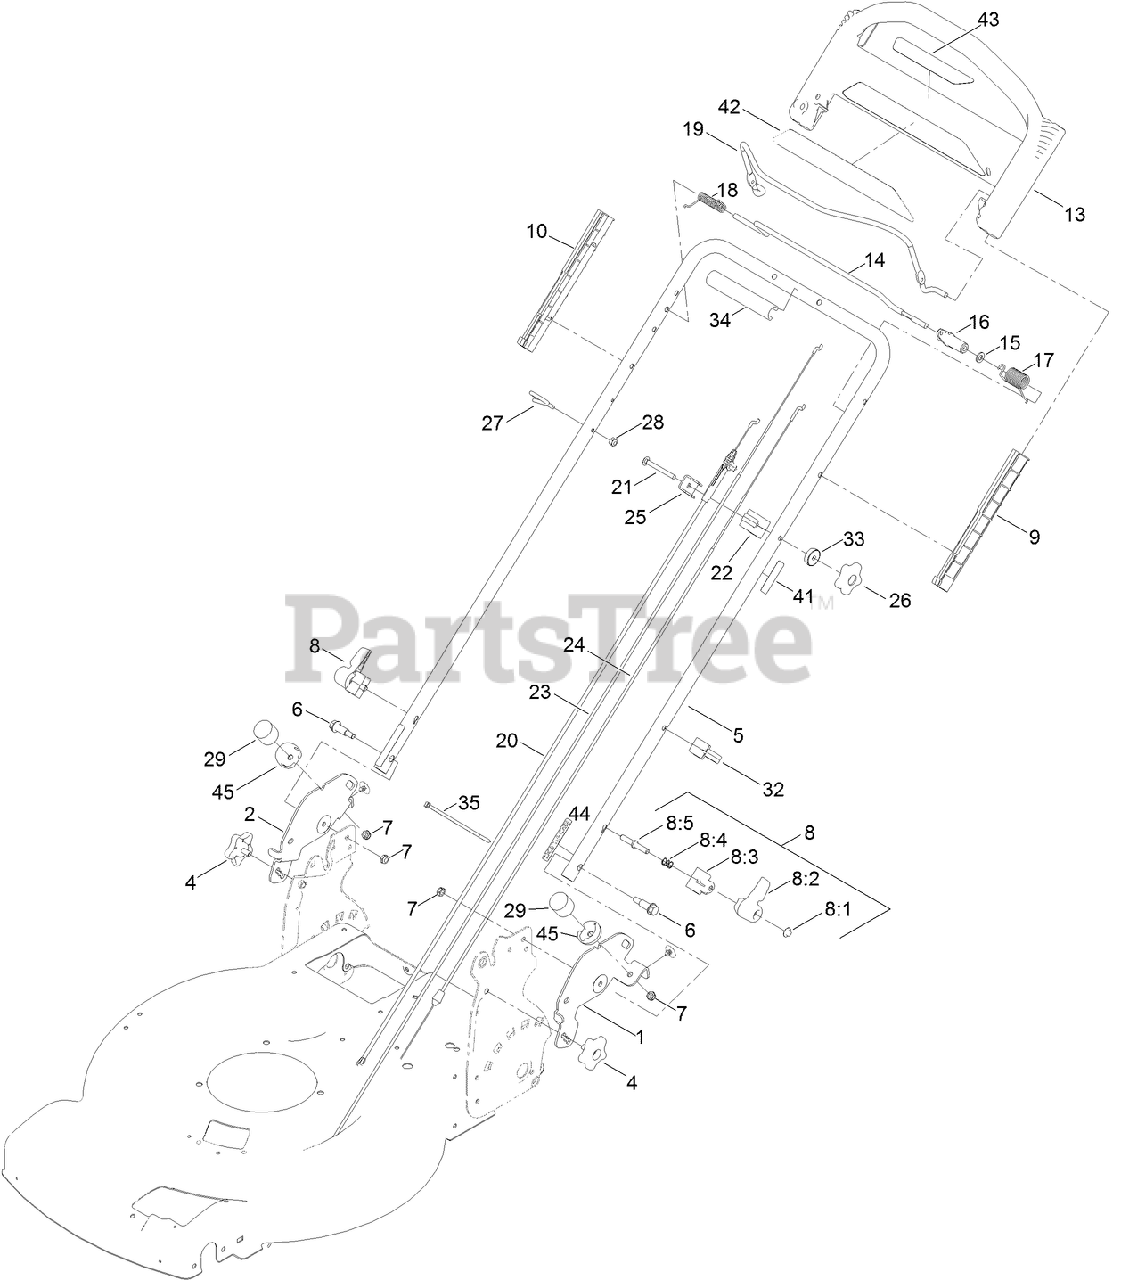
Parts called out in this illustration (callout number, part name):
1	BRACKET-FLOAT, LH
2	BRACKET-FLOAT, RH
4	KNOB-HANDLE
5	HANDLE-UPPER
6	BOLT-SHOULDER
7	NUT-LOCK, NI
8	QUICK RELEASE ASM
8:2	LEVER
8:3	ANCHOR-SPRING
8:4	SPRING-COMPRESSION
8:5	ROD-RELEASE
9	GUIDE-LH
10	GUIDE-RH
13	HANDLE-PACE, PERSONAL
14	BAR-CONTROL, TRACTION
15	WASHER-PLAIN
16	LEVER-TRACTION
17	SPRING-TORSION
19	BAIL-BRAKE
20	CABLE-BRAKE
21	SCREW-CARR
22	MOUNT-CABLE, TRACTION
23	CABLE-TRACTION, FRONT
24	CABLE-TRACTION, REAR
25	CLAMP-CABLE
26	KNOB-HANDLE, LOCKING
27	GUIDE-ROPE
28	NUT-LOCK, NI
29	BUMPER-RUBBER
32	GUIDE-CABLE
33	WASHER-CURVED
34	HANDLE-COVER
35	TIE-CABLE
41	DECAL-ADJUSTMENT
42	DECAL-POWEREVERSE
43	DECAL-INSTRUCTION, DRIVE
44	DECAL-ISOFLEX
45	COVER-BUMPER
